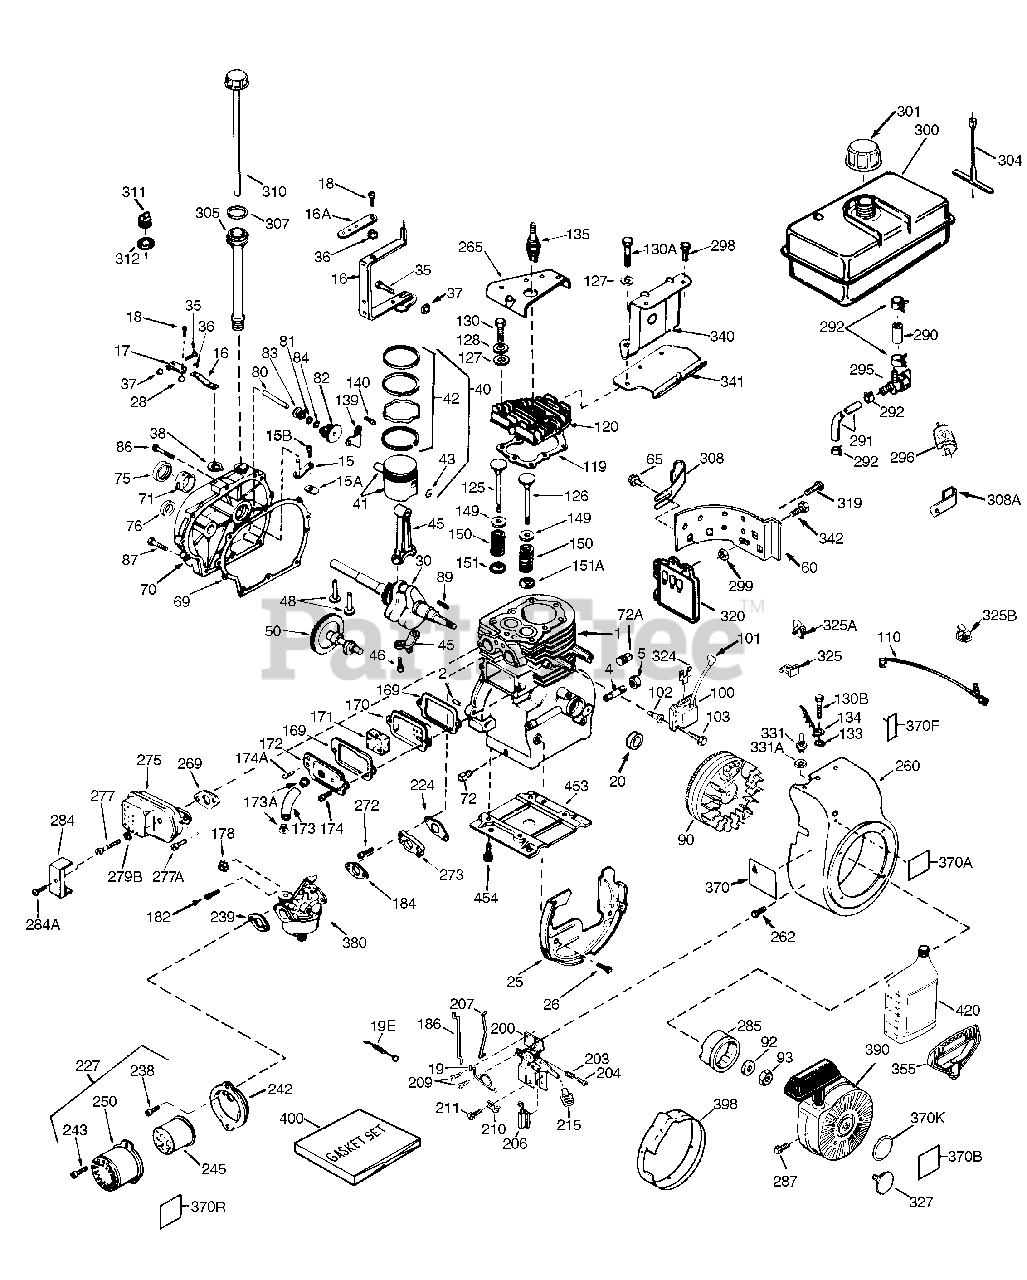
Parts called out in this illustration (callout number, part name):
1	"Cylinder (Incl. 2, 20 & 72)
2	Dowel Pin
15	Governor Rod (Incl. 15A & 15B)
15A	Governor Yoke
15B	Screw, 6-40 x 5/16"
16	Governor Lever
17	Governor Lever Clamp
18	Screw, 8-32 x 5/16"
19	Speed Control Spring
20	Oil Seal
25	Blower Housing Baffle
26	Screw, 1/4-20 x 5/8"
28	Lock Nut, 8-32
30	Crankshaft
35	Screw, 10-32 x 3/4"
36	Lock Washer #8
37	Lock Nut, 10-32
38	Retaining Ring
40	Piston, Pin & Ring Set (Std.)
40	Piston, Pin & Ring Set (.010" OS)
40	Piston, Pin & Ring Set (.020" OS)
41	Piston & Pin Ass'y. (Std.) (Incl. 43)
41	Piston & Pin Ass'y. (.010" OS) Incl. 43
41	Piston & Pin Ass'y. (.020" OS) Incl. 43
42	Ring Set (Std.)
42	Ring Set (.010" OS)
42	Ring Set (.020" OS)
43	Piston Pin Retaining Ring
45	Connecting Rod Ass'y. (Incl. 46)
46	Connecting Rod Bolt
48	Valve Lifter
50	Camshaft (BCR)
60	Blower Housing Extension
65	Screw, 10-24 x 1/2"
69	* Cylinder Cover Gasket
70	Cylinder Cover (Incl. 75 & 80)
72	Oil Drain Plug (Sq. hd., 1/4-18)
75	Oil Seal
80	Governor Shaft
82	Governor Gear Ass'y. (Incl. 81)
83	Governor Spool
84	Retaining Ring
86	Screw, 1/4-20 x 1-1/4"
87	Screw, 1/4-20 x 1-3/4"
89	Flywheel Key
90	Flywheel
92	Belleville Washer
93	Flywheel Nut
100	Solid State Ignition
101	Spark Plug Cover
102	Solid State Mounting Stud
103	Screw, Torx T-15, 10-24 x 1"
110	Ground Wire
119	* Cylinder Head Gasket
120	Cylinder Head (Incl. 3 of 130)
125	Exhaust Valve (Std.)(Incl. 151)
125	Exhaust Valve (1/32" OS) (Incl. 151)
126	Intake Valve (Std.) (Incl. 151)
126	Intake Valve (1/32" OS) (Incl. 151)
128	Belleville Washer
130	Screw, 5/16-18 x 2-1/2"
135	Resistor Spark Plug - RJ17LM
139	Governor Gear Bracket
140	Screw, Torx T-25, 10-24 x 1/2"
149	Valve Spring Cap
150	Valve Spring
151	Valve Spring Keeper
169	* Valve Cover Gasket
170	Breather Body
171	Breather Element
172	Valve Cover
173	Breather Tube
173A	Breather Tube Grommet
174	Screw, 10-24 x 1/2"
182	Screw, 1/4-20 x 27/32"
184	* Carburetor To Intake Pipe Gasket
186	Governor Link
200	Control Bracket (Incl. 19, 203 & 204)
203	Compression Spring
204	Screw, 5-40 x 7/16"
206	Terminal
207	Throttle Link
209	Screw, 10-32 x 1/2"
210	Conduit Clip
211	Screw, 10-32 x 3/8"
224	* Intake Pipe Gasket
227	Air Filter Elbow Ass'y. (Inc. 228, 23 2, 239A & 240) 39A&242)
238	Screw, 10-32 x 7/8"
239	* Air Cleaner Gasket
242	Air Cleaner Base
245	Air Filter
250	Air Cleaner Cover
260	Blower Housing
262	Screw, T-40, 5/16-24 x 21/32"
265	Cylinder Head Cover
269	* Exhaust Manifold Gasket
272	Screw, 5/16-18 x 3/4"
273	Carburetor Flange
275	Muffler
285	Starter Cup
287	Screw, 8-32 x 21/64"
291	Fuel Line
292	Fuel Line Clamp
298	Screw, 1/4-15 x 3/4"
299	"U" Type Clip
300	Fuel Tank (Incl. 292 & 301)
301	Fuel Cap (Red)
305	Oil Fill Tube
307	"O" Ring
308	Fill Tube Clip
310	Dipstick
324	Terminal
325	Wire Clip
325A	Wire Clip
327	Starter Plug
340	Fuel Tank Bracket
341	Fuel Tank Bracket
342	Screw, 1/4-20 x 5/8"
370	Instruction Decal
370A	Name Decal
370B	Decal - Important Lubrication - SAE 3
370C	Instruction Decal
380	Carburetor (Incl. 184)
390	Rewind Starter
400	* Gasket Set (Incl. items marked PK in notes) Incl. part #'s 26756 (1), 2727 2A (1), 27896A (2), 27915A (1), 29673 (1), 30684 (1), 31688A (1), 33629 (1 ), 34912 (1), 35865 (1), 36445 (1)
420	SAE 30 4-Cycle Engine Oil (Quart)
453	Engine Mounting Base
454	Screw, 5/16-18 x 3/4"
